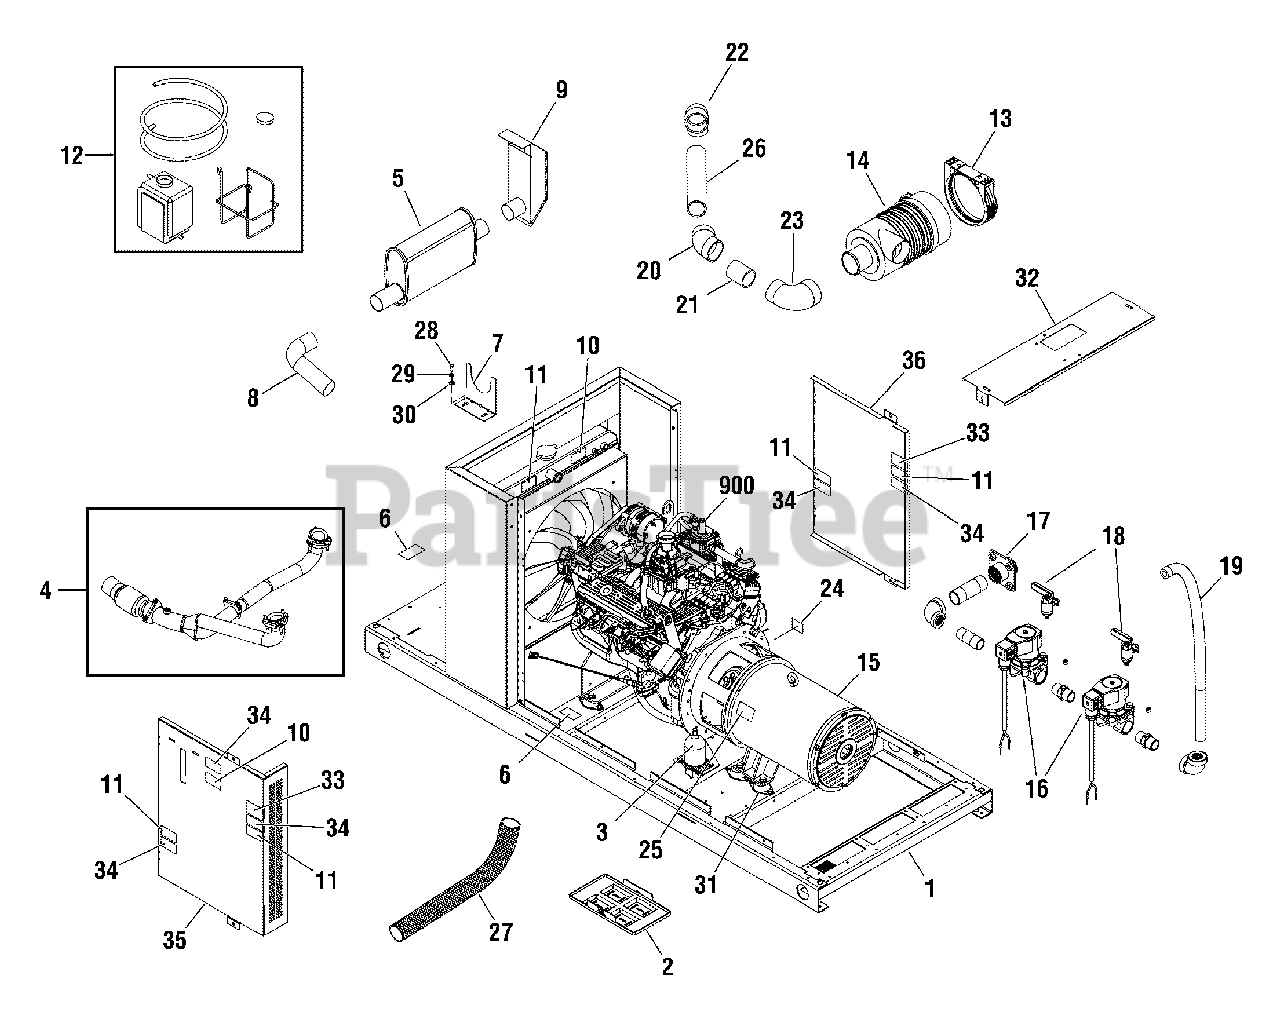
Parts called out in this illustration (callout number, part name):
4	KIT, Exhaust
5	MUFFLER
6	DECAL
7	BRACKET, Muffler
9	DIFFUSER
11	DECAL
12	BOTTLE, Overflow
24	DECAL
28	* CAPSCREW, Hex Head, 1/4-20 x 3/4
29	* WASHER, Lock, 1/4-M6
30	* WASHER, Flat, 1/4
31	MOUNT, Vibration
33	DECAL
34	DECAL
900	** ENGINE
